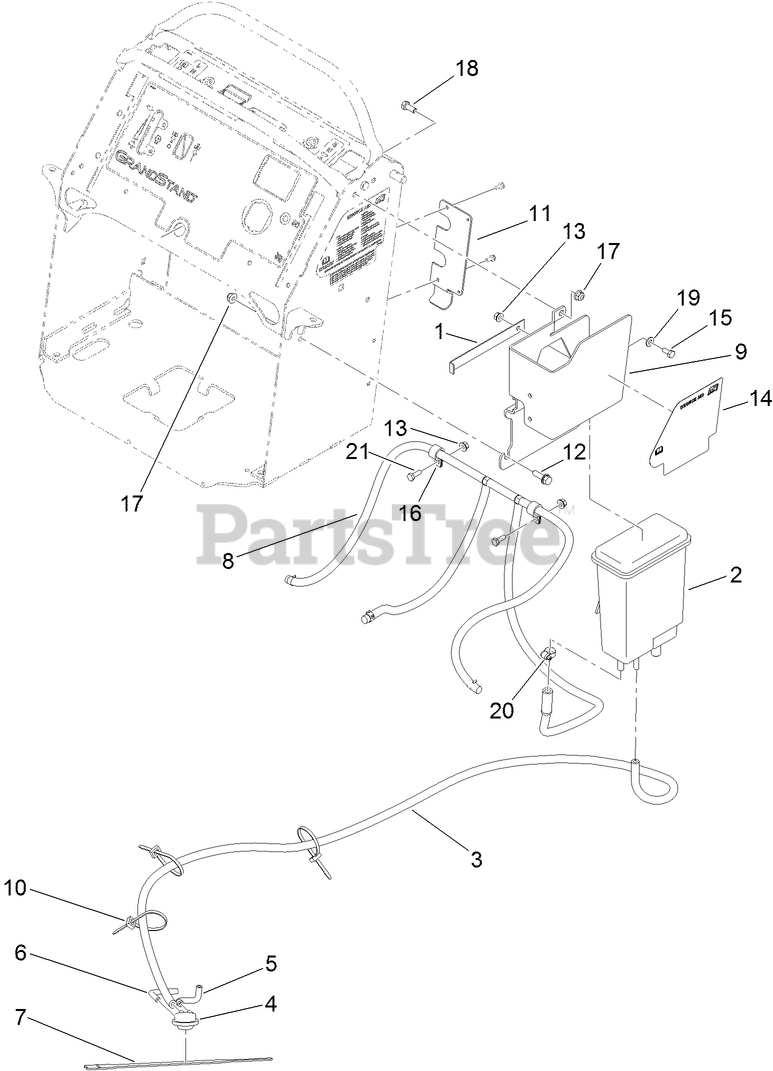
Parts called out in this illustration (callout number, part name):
1	PLATE-LOC
2	CANISTER-CARBON, 1200CC
3	HOSE-FUEL
4	VALVE-CONTROL, VACUUM
5	HOSE-VENT, FORMED
6	HOSE-VENT, FORMED
7	STRAP-VELCRO, CABLE TIE
8	VENT HOSE ASM
9	PLATE- ADAPTER
10	TIE-CABLE
11	PLATE- MANUAL TUBE
12	SCREW-HHF
13	NUT-HHF
14	DECAL-AID, SERVICE
15	SCREW-HH
16	CLAMP-CABLE
17	NUT-HF, NI
18	SCREW-HH
19	WASHER-FLAT
20	CLAMP-WORM
21	SCREW-HH
